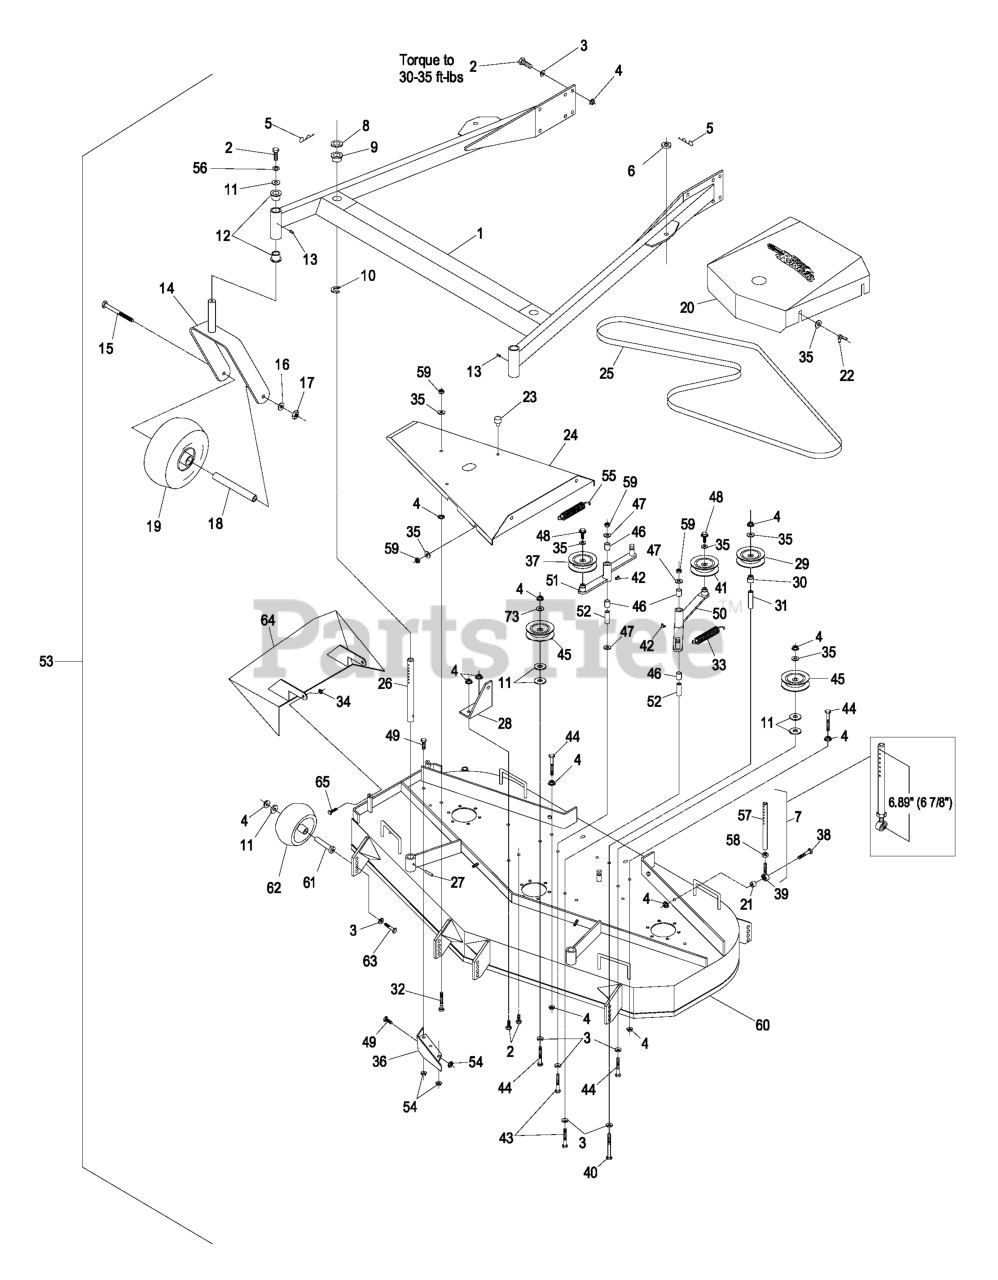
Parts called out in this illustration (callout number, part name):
1	SUPPORT ASSY-FMD60
2	SCREW-HH
3	WASHER-BELLEVILLE
4	NUT-HHF, WHIZ
5	Hairpin, .177
8	SPACER-DECK SUPPORT
9	BUSHING-DECK
10	RING-RETAINING
12	BEARING-FLANGED
13	FITTING-GREASE
15	SCREW-HH
16	WASHER-LOCK
17	NUT-HH
18	SPACER
22	NUT-WING
24	WLD,DECK COVER
25	BELT-DRIVE, BLADE
26	ROD,DECK SUPPORT
28	BRACKET,SPRING ANCHOR
29	PULLEY-IDLER
30	BUSHING,IDLER
31	SPACER-ANCHOR, CLUTCH
33	SPRING-EXTENSION
34	NUT-LOCK, NI
35	WASHER-FLAT
36	WLD,BAFFLE DISCHARGE
37	IDLER,PULLEY
38	SCREW-HH
39	BALLJOINT
40	SCREW-HH
41	PULLEY-IDLER
42	FITTING-GREASE, 90 DEG
43	SCREW-HH
44	SCREW-HH
45	IDLER,PULLEY
46	SLEEVE-BEARING
47	WASHER-FLAT
48	Bolt, Whizlock 3/8-16 X 1
49	SCREW-HH
50	Arm, Deck Drive Idler
52	BUSHING-PIVOT, IDLER
55	SPRING-EXTENSION
56	WASHER-LOCK
57	LINK,SUPPORT
58	NUT-HEX
59	NUT-LOCK, NI
61	BUSHING-ROLLER
62	ROLLER-SCALP, ANTI
63	SCREW-HH
65	SCREW-HH
66	KIT, SP CASTER WHEEL REPL
